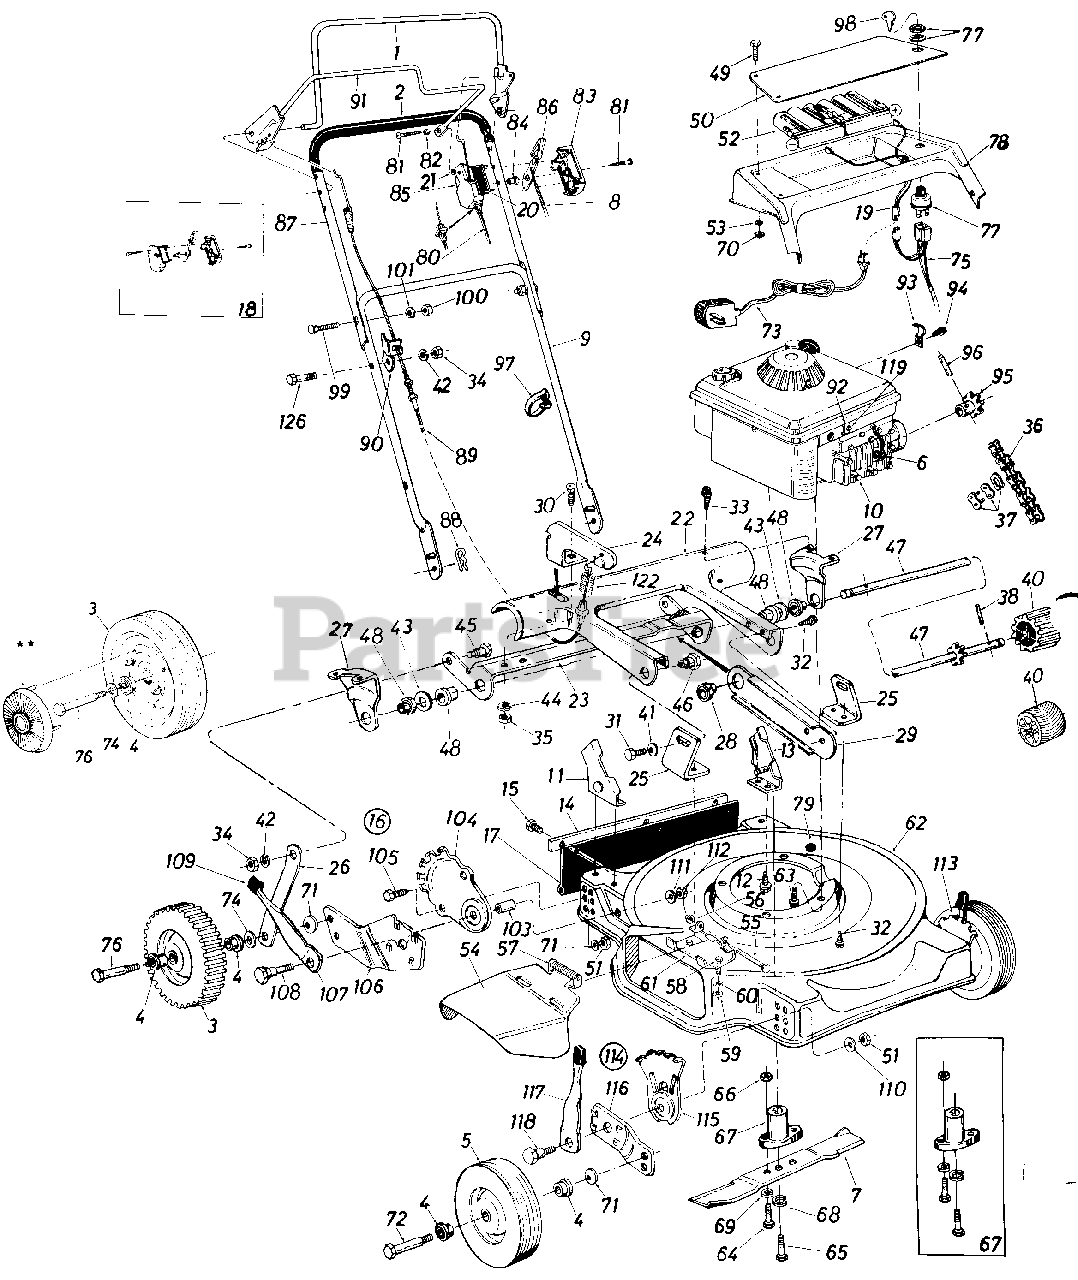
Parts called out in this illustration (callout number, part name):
1	Control Handle Ass'y.-L.H.
2	Grip
3	Rear Wheel Ass'y. Comp.-9 x 1.75
4	Flange Brg.-1/2" I.D.
5	Front Wheel Ass'y. Comp.
6	Spark Plug Boot
7	Blade 22"
8	Throttle Wire-53.0"
9	Lower Handle
10	Engine
11	Handle Brkt. Ass'y.-R.H.
12	Hex Wash. Hd. "B"-Tap Scr. 5/16-18 x .50" Lg.
13	Handle Brkt. Ass'y.-L.H.
14	Retainer Strip
15	Hex AB-Tap Scr. 1/4 x .62" Lg.
16	R.H Height Adj. Comp.
17	Rear Flap Ass'y.
18	Kit-Control Housing Comp.
19	Battery Pack Lead
20	Control Label
21	Flat Wash. .203" I.D. x .406" O.D.
22	Pinion Pivot Cover 22"
23	Cam
24	Engagement Arm
25	Pivot Brkt.
26	Link
27	Axle Brkt.
28	Flanged Ball Brg. .500" I.D.
29	Brg. Support
30	Carriage Bolt 1/4-20 x .50" Lg.
31	Hex Bolt 3/8-16 x .50" Lg.
32	Hex "B"-Tap Scr. 1/4" x .38" Lg.
33	Hex Wash. Hd. "AB"-Tap Scr. 1/4" x .62" Lg.
34	Hex Nut 5/16-18 Thd.*
35	Hex Nut 1/4-20 Thd.
36	#48 Chain 1/2" Pitch 49 Li nks
37	#48 Master Link
38	Spring Pin Spir. 3116" Dia. x 1.25" Lg.
40	Drive Pinion
41	Bell-Wash. .400" I.D. x .88" O.D. x .060
42	L-Wash. 5/16" I.D.
43	Fl-Wash. .531" I.D. x .930" O.D. x .050
44	L-Wash. 1/4" I.D.
45	Shld. Bolt .437" Dia. x .162
46	Shld. Nut .625" Dia. x .162
47	Pinion Shaft w/7 Tooth Sprocket
48	Flange Brg. .506" I.D.
49	Fl-Hd. Phil. Scr. #8-32 x .38" Lg.
50	Battery Plate
51	Hex Nut 3/8-16 Thd.
52	Battery Pack
53	External L-Wash. #8 I.D.
54	Chute Deflector Ass'y. Comp.
55	Pivot Pin
56	Cap Speed Nut 1/4" Rod
57	Torsion Spring
58	Hex Bolt 1/4-20 x .50" Lg.
59	Hex Nut 1/4-2 Thd.
60	L-Wash. 1/4" I.D.
61	Hinge Plate
62	22" Deck Ass'y.
63	Hex Wash. Hd. TT-Tap Scr. 3/8-16 x 1.0" Lg.
64	Hex Bolt 5/16-24 x 1.00" Lg. (Grade 5)
65	Hex Bolt 3/8-24 x 2.25" Lg. (Grade 5)
66	Hex Nut 5/16-24 Thd.
67	Blade Adapter Kit
68	L-Wash. 3/8" I.D.-H.D.
69	L-Wash. 5/16" I.D.
70	Hex Nut #8-32 Thd.
71	Bell-Wash. .40" I.D. x .88" O.D.
72	Front Axle Bolt
73	Battery Charger
74	Fl-Wash. .531" I.D. x .93" O.D.
75	Wire Harness
76	Rear Axle Bolt
77	Ignition Switch
78	Handle Panel
80	Control Cable-39.0"
81	Truss Mach. Self-Tap Scr. #12 x 1.50" Lg.
82	Spacer.23" I.D.
83	Control Panel Half
84	Control Disc Pin
85	Clutch Panel Half
86	Throttle Control Lever
87	Upper Handle
88	Hairpin Cotter
89	Clutch Cable w/Spring
90	Cable Mtg. Brkt.
91	Drive Control Handle
92	Casing Clamp
93	Casing Clamp
94	Hex "B"-Tap Scr. #10 x .38 "
95	10 Tooth Sprocket Ass'y.
96	Spiral Pin 3/16" Dia. x 1.00"
97	Cable Tie
98	Ignition Key
99	Curved Hd. Carriage Bolt 5/16-18 x 1.38" Lg.
100	Hex Nut 5/16-18 Thd.
101	L-Wash. 5/16" I.D.
103	Spacer.395" I.D. x .503" O.D. x .562" Lg.
104	Index Plate
105	Hex Bolt 3/8-16 x .75" Lg.
106	Pivot Bar R.H.
107	Spring Lever
108	Shoulder Bolt .500" Dia. x 3.75" Lg.
109	Spring Lever Knob
110	Bell-Wash. .39 I.D. x 1.4 O.D.
111	Bell-Wash. .336" I.D. x .860 O.D.
112	Hex L-Nut 5/16-18 Thd.
113	Height Adj. Ass'y.-Comp.
114	Height Adj. Ass y.-Comp.
115	Height Adj. Plate
116	Pivot Bar
117	Spring Lever Ass'y. w/Knob
118	Shoulder Bolt .500" Dia. x .375" Lg.
119	Hex Sems #10-32 x .62" Lg.
122	Compression Spring .47" O.D. x 1.93" Lg.
126	Hex Bolt 5/16-18 x 1.25" Lg.*
